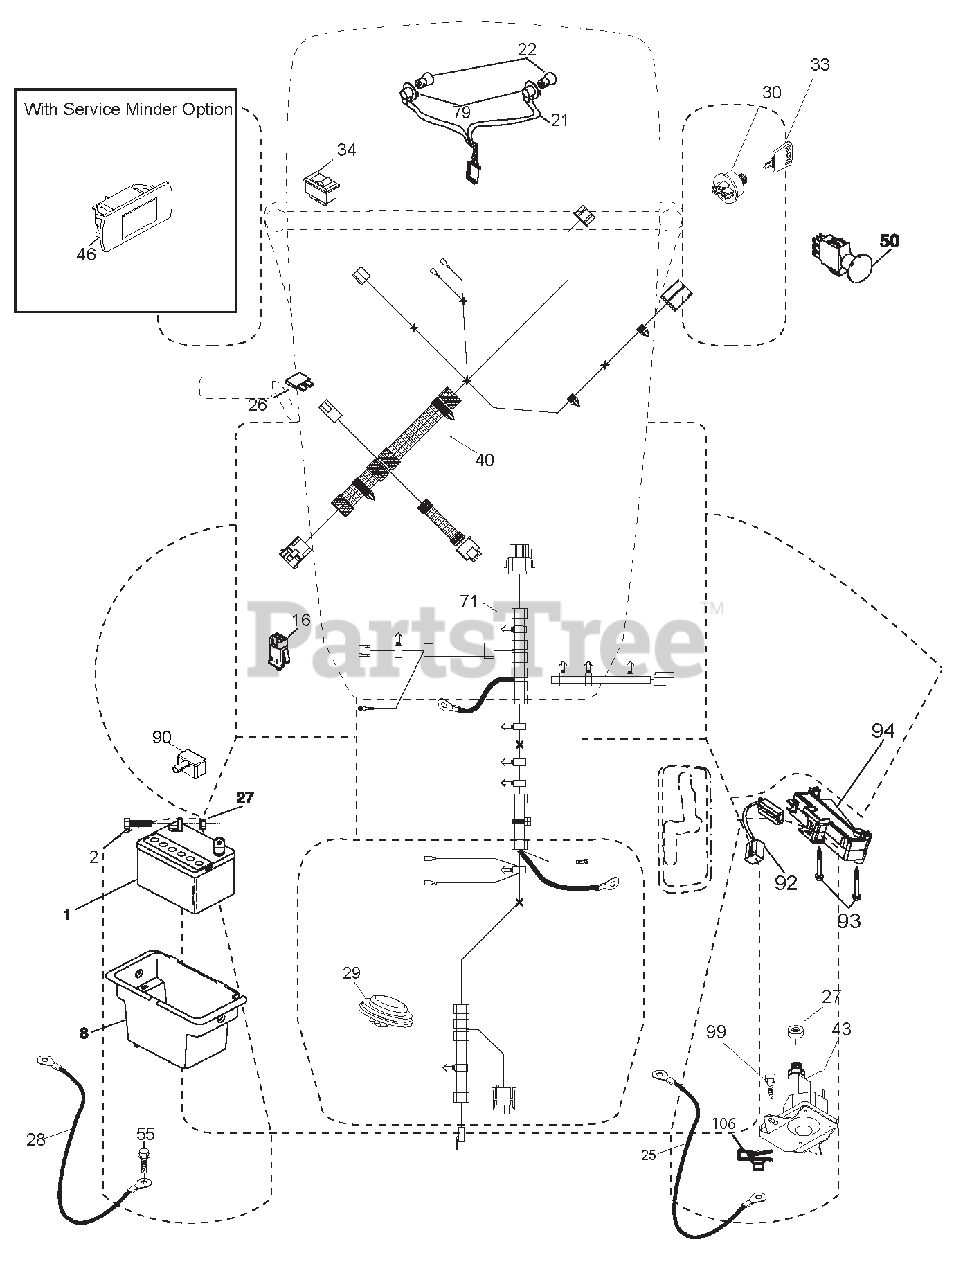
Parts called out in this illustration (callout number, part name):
1	BATTERY.12.VOLT.28.AMP.WET
2	BOLT.HEX.HD.1/4-20UNC X 3/4
8	BOX.BATTERY.MNT.REAR.LT.TEX.BL
16	SWITCH.INTERLOCK.NONO.GRAY
21	HARNESS ASM.LIGHT.22"(4152J)
22	BULB.LIGHT.#1156
25	CABLE STARTER 6 G4. BL/RED14.5
26	FUSE.20 AMP.
27	Nut, Keps Hex 1/4-20 unc
28	CABLE.BLACK.22"REAR BATT.TEX
29	SWITCH.SEAT.DELTA.OPC.9LB.
30	SWITCH.IGN.DLTA.P-IN.ROS
33	KEY/CHAIN.BLISTER PACK.GEN.USA
34	SWITCH.LIGHT/RESET.B/B/RED.
40	HARNESS IGN ELEC RELAY
43	SOLENOID.W/BRASS PLUNGER.2005
46	HOUR METER
50	SWITCH.PTO.8 TERMINAL.BLACK
55	SCREW.5/16-18X3/4.SMGML.TAP/R
71	HARNESS.IGN.CHASSIS.TEX
79	SOCKET ASM.BULB.TWISTLOCK
90	COVER TERMINAL BATTERY FR. TEX
92	HARNESS.PIGTAIL.CONSLE.ROS.MLK
93	SCREW.PLASTITE.10-14 X 2.0
94	MODUAL REVERSE ROS
